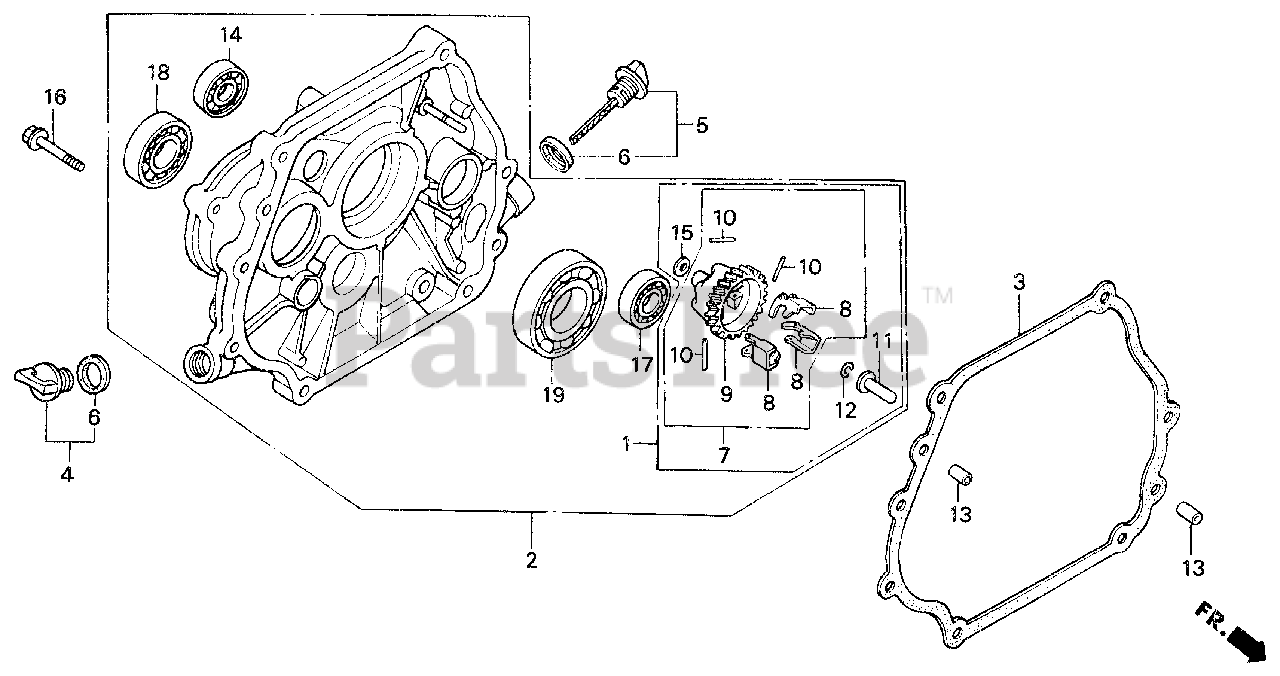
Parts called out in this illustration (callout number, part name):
1	GOVERNOR KIT
2	COVER ASSY., CRANKCASE (L-TYPE)
3	GASKET, CASE COVER
4	CAP ASSY., OIL FILLER
5	CAP ASSY., OIL FILLER
6	GASKET, OIL FILLER CAP
7	GOVERNOR ASSY.
8	WEIGHT, GOVERNOR
9	HOLDER, GOVERNOR WEIGHT
10	PIN, GOVERNOR WEIGHT
11	SLIDER, GOVERNOR
12	CLIP, GOVERNOR HOLDER
13	PIN, DOWEL (8X12)
14	BEARING, RADIAL BALL (6202)
15	WASHER, PLAIN (6MM)
16	BOLT, FLANGE (8X40)
17	BEARING, RADIAL BALL (6202)
18	BEARING, RADIAL BALL (6204)
19	BEARING, RADIAL BALL (6207)
